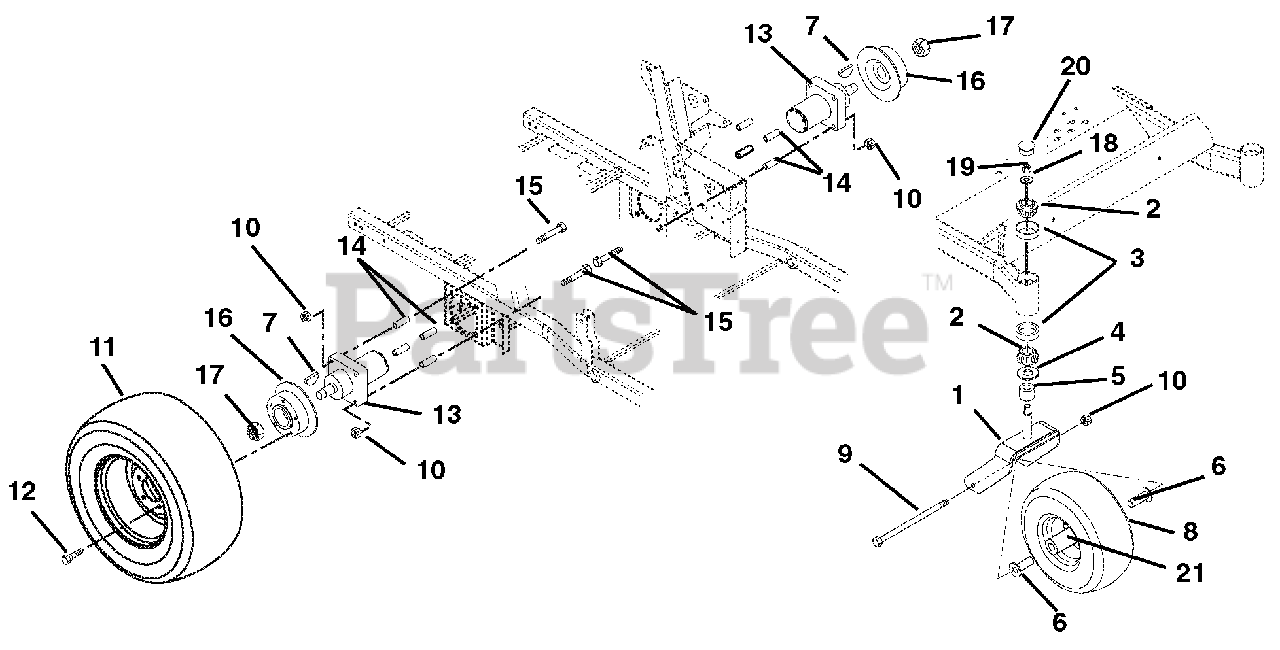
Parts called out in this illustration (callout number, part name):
1	Fork
2	Bearing, Cone with Grease
3	Bearing, Cup 1.98 x .420
4	Bearing Seal 1.5 x 2 x .18
5	Spacer, PM, 1.03 I.D. x 1.5 O.D. x .375
6	Spacer, Wheel
7	Key, Woodruff .31 x 1.00 (Included with 13)
8	Wheel/Tire Assembly, 15 x 6.00-6
9	Bolt, Hex .50-13 x 9.00 Grade 5
10	Nut, Locking Top Flange .50-13
11	Wheel, Tire 23 x 10.00 - 12
12	Bolt, Lug Grade 8 .50-20 UNF x 1.38 Long 60 Degree
13	Hydraulic Wheel Motor (includes 17 & 7) (991029, 030, 032)
14	Bushing, Sleeve .513 x .748 x 2.13
15	Bolt, Hex .50-13 x 5.00 Grade 8
16	Hub and Disc
17	Nut, Lock Jam Patch (Included with 13)
18	Washer, Flat, Steel .812 x 1.50 x .135
19	Nut, Jam Center Lock .75-16
20	Cap, Dust
21	Bearing, 25mm I.D. x 52mm O.D. x 15mm
